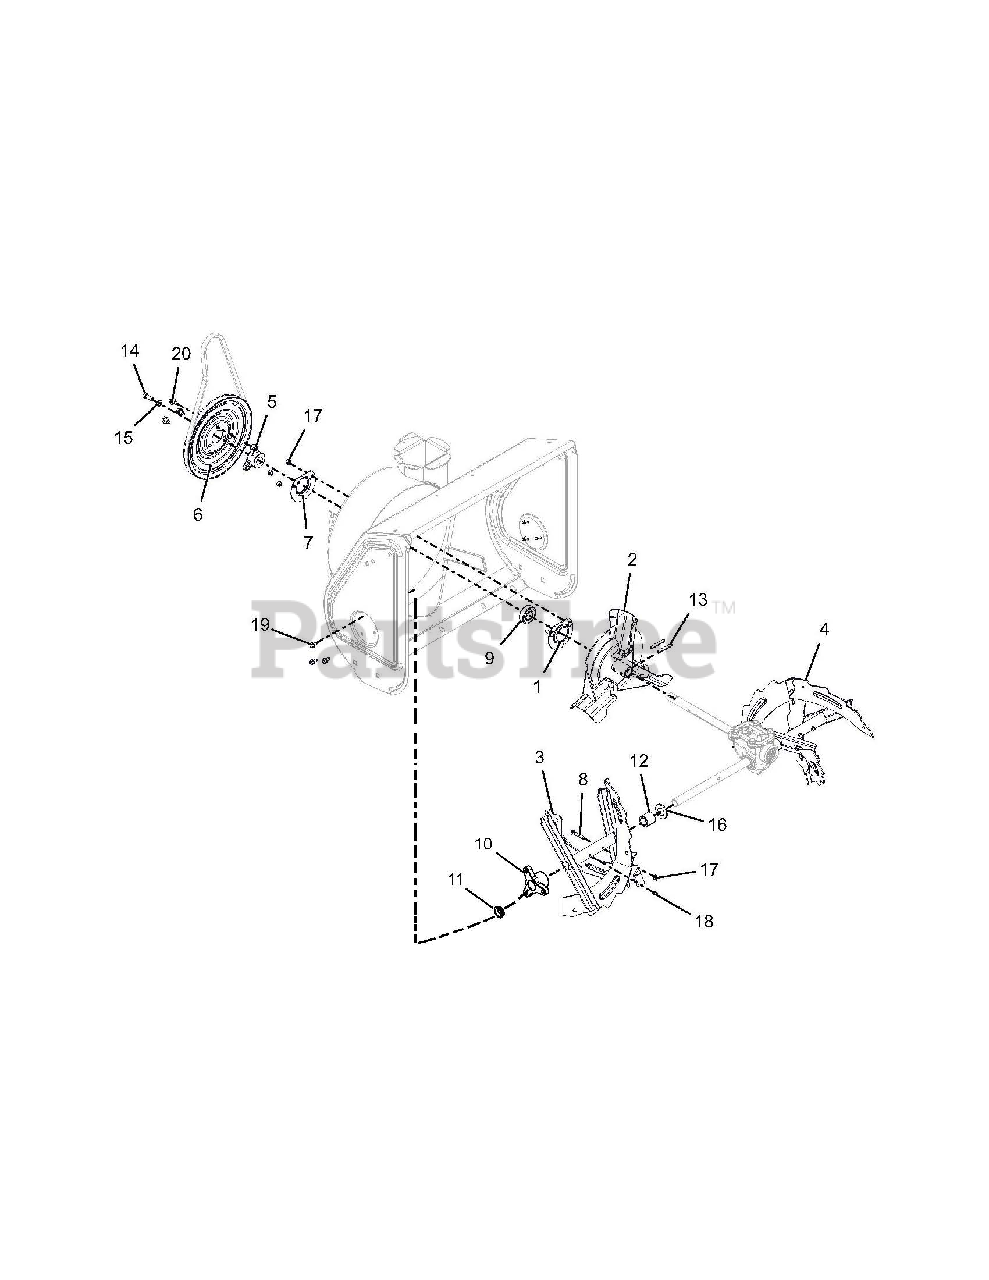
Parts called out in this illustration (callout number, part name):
1	BEARING FLANGE
2	IMPELLER, COMPACT 12" 3-BLADE
3	AUGER, 20" RH, BLK SERR W/ZERK
4	AUGER, LH 20", BLK SERR W/ZERK
5	PULLEY HUB, BOLT-ON D-BORE .75
6	PULLEY,SPIN FORM SINGLE GROOVE
7	BEARING FLANGE
8	SHEAR BOLT
9	BRG-BALL .750X1.750X.50
10	BUSHING, RAKE SHAFT .75"
11	BSHG-FLG SPLIT NYLINER .75"ID
12	BSHG-SLV .75X1.12X1.062 NYL BK
13	PIN-ROLL .250X1.75
14	BLT-HEX .31-24X.75 YWZC GR5
15	WSHR-LK .312X.097 HVY YWZC
16	@WSHR-FL-STL.812X1.50X.135YWZC
17	@NUT-LK-CTR .25-20 YWZC
18	ZERK,FITTING .25X.125 DRIVE IN
19	SCR-TAP .25-20X.50 HWH TR YWZ
20	@SCR-TAP .31-18X.50 HWH TR YWZ
